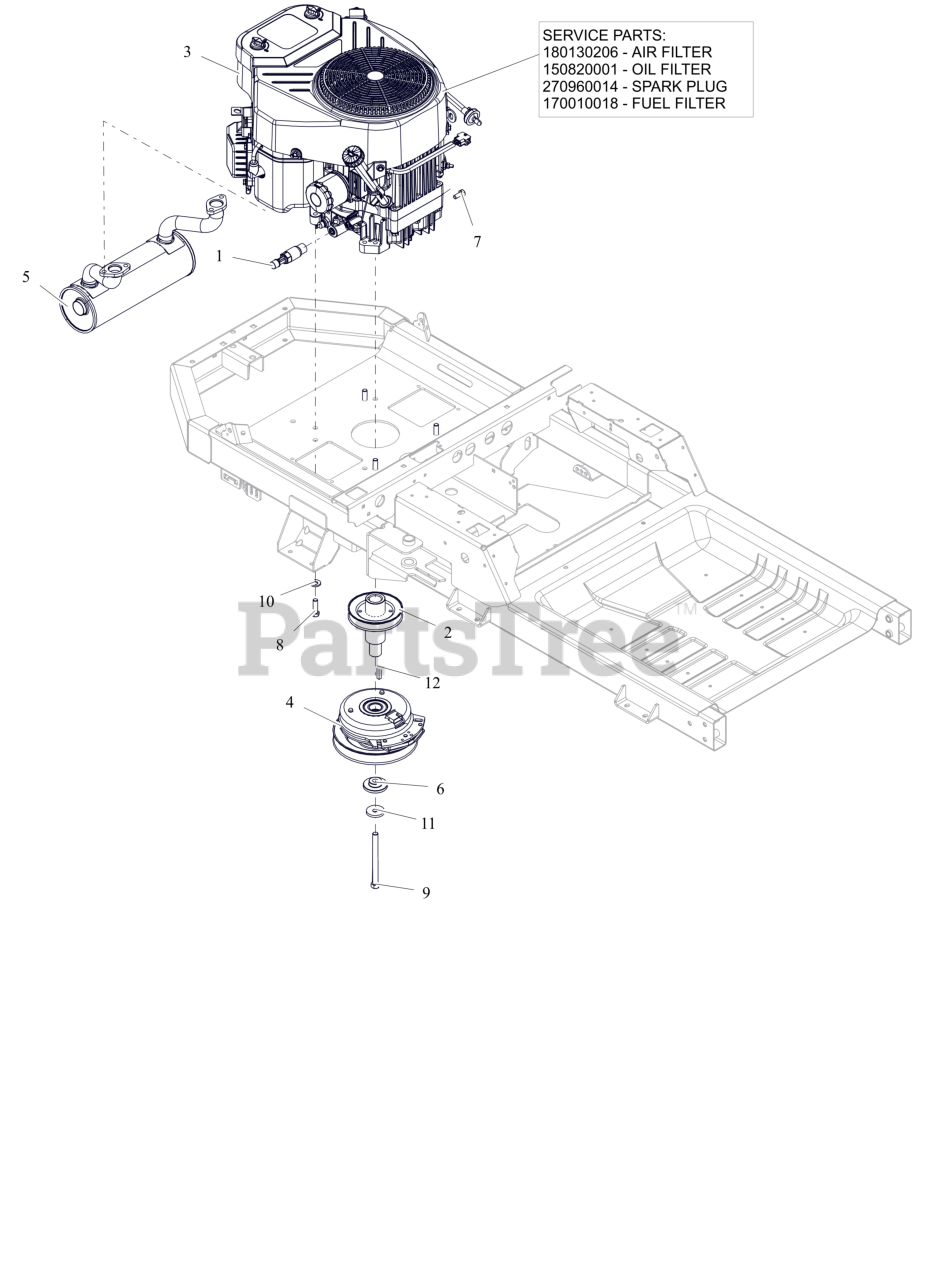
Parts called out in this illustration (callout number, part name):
1	ASM, ENGINE OIL DRAIN VALVE KAWASAKI
2	WLDMT, DRIVE SHEAVE (LONG)
3	ENGINE, LONCIN 764cc
3	AIR FILTER
3	OIL FILTER
3	SPARK PLUG
3	FUEL FILTER
4	CLUTCH,105FTLB MONOPOLE 6.83"
5	ASM, LONCIN MUFFLER 2P80F
6	BSHG-FLG .469X1.06X.574X2.0
7	BLT, HEX M8-1.25X20 G8.8 ZCC
8	BLT, HEX .38-16X1.25 G5 ZCC NT
9	BLT, HEX .44-20X5.00 G8 ZCC NT
10	WASHER, 3/8" SPRING DISC
11	WASHER, 7/16" SPRING DISK
12	KEY-SQ .25 X 1.25 X .25 SAE
